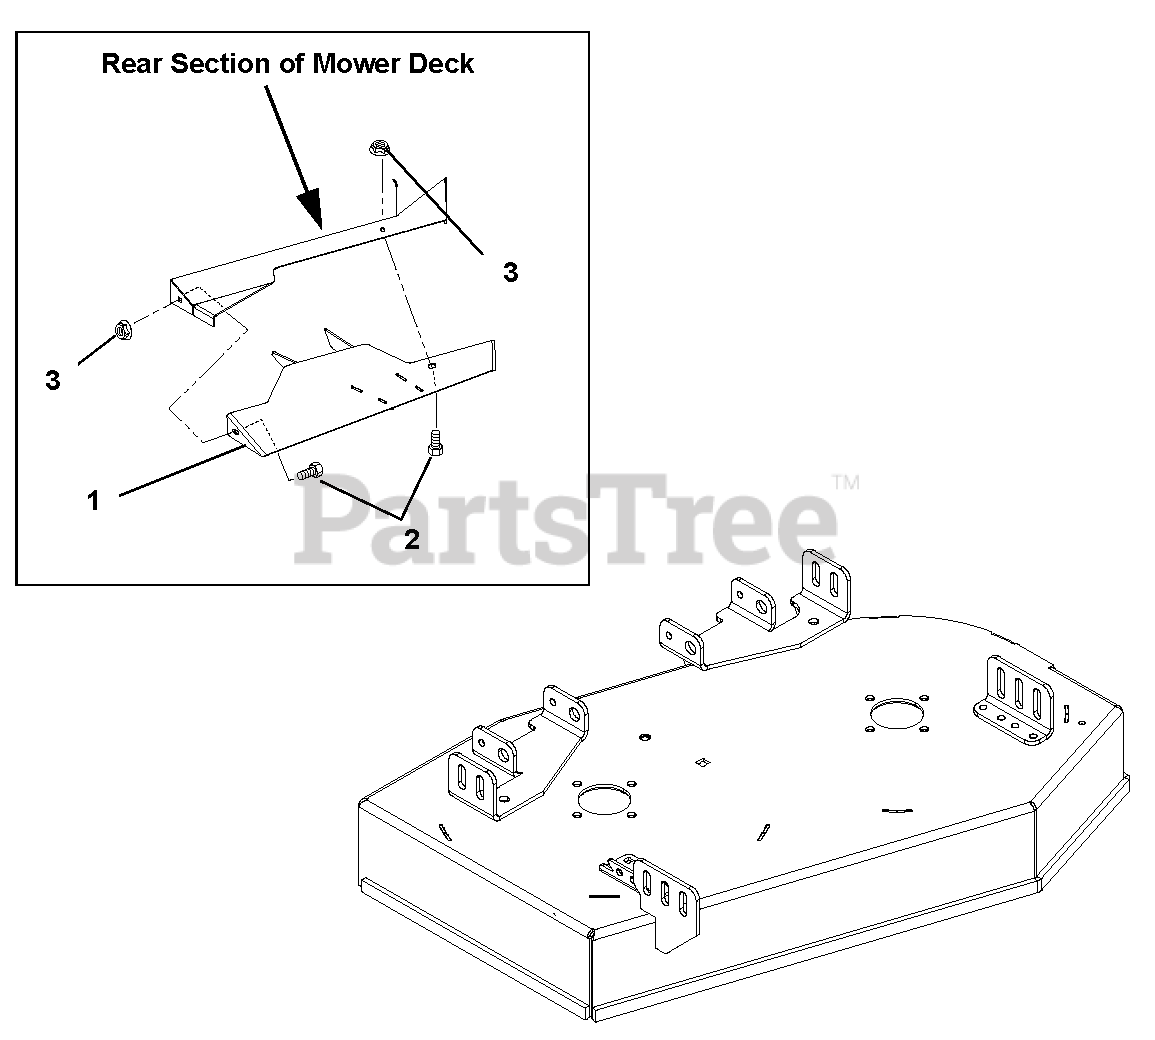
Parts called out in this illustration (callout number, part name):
1	34" Deflector Extension-Rear Discharge
2	Bolt, Hex .31-18 x .75
3	Nut, Locking-Top Flange .31-18
